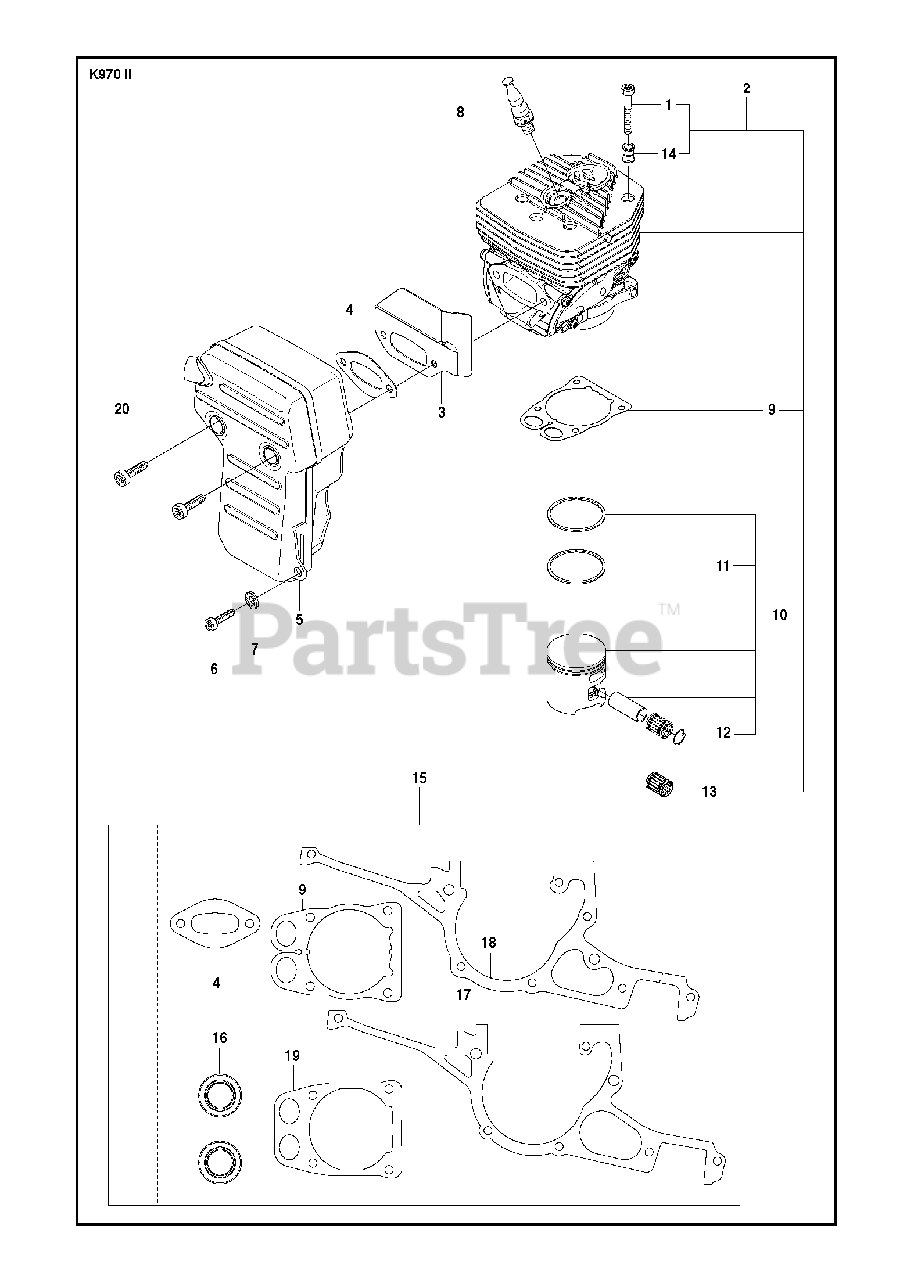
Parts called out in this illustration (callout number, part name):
1	SCREW ITXSCM
2	CYLINDER ASSYIncl. 9 - 10, 13
3	HEAT DEFLECTOR
4	GASKET
5	MUFFLER ASSY
6	SCREW ITXSCM
8	DECOMPRESSION VALVE
9	GASKETPaper gasket
10	PISTONIncl. 11 - 12
13	NEEDLE BEARING
15	GASKET KITIncl. 4, 9, 15 - 16
16	SEALING RING
19	GASKETMetal gasket
20	SCREW ITXSCM
